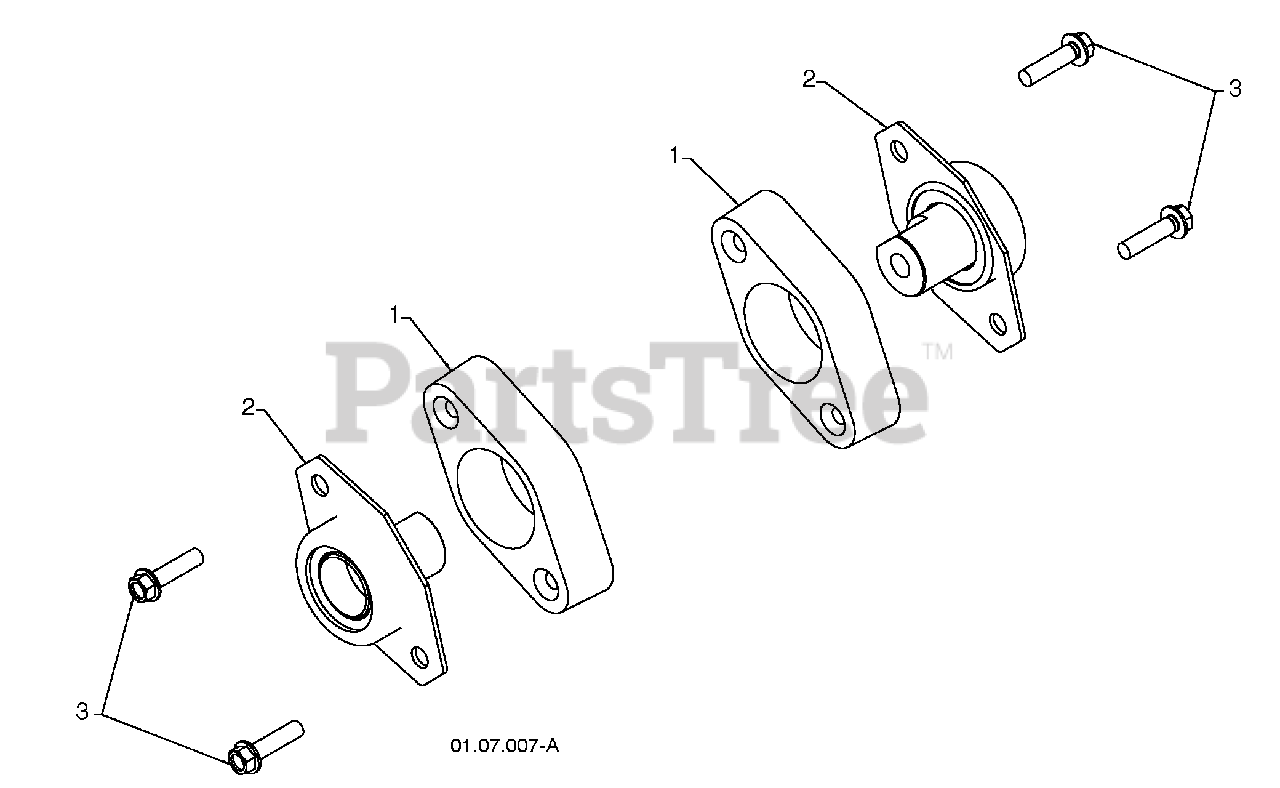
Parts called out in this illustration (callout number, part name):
1	PLASTIC RETAINER
2	AUGER BALL BEARING
3	SCREW 5/16-18 X 1.00
